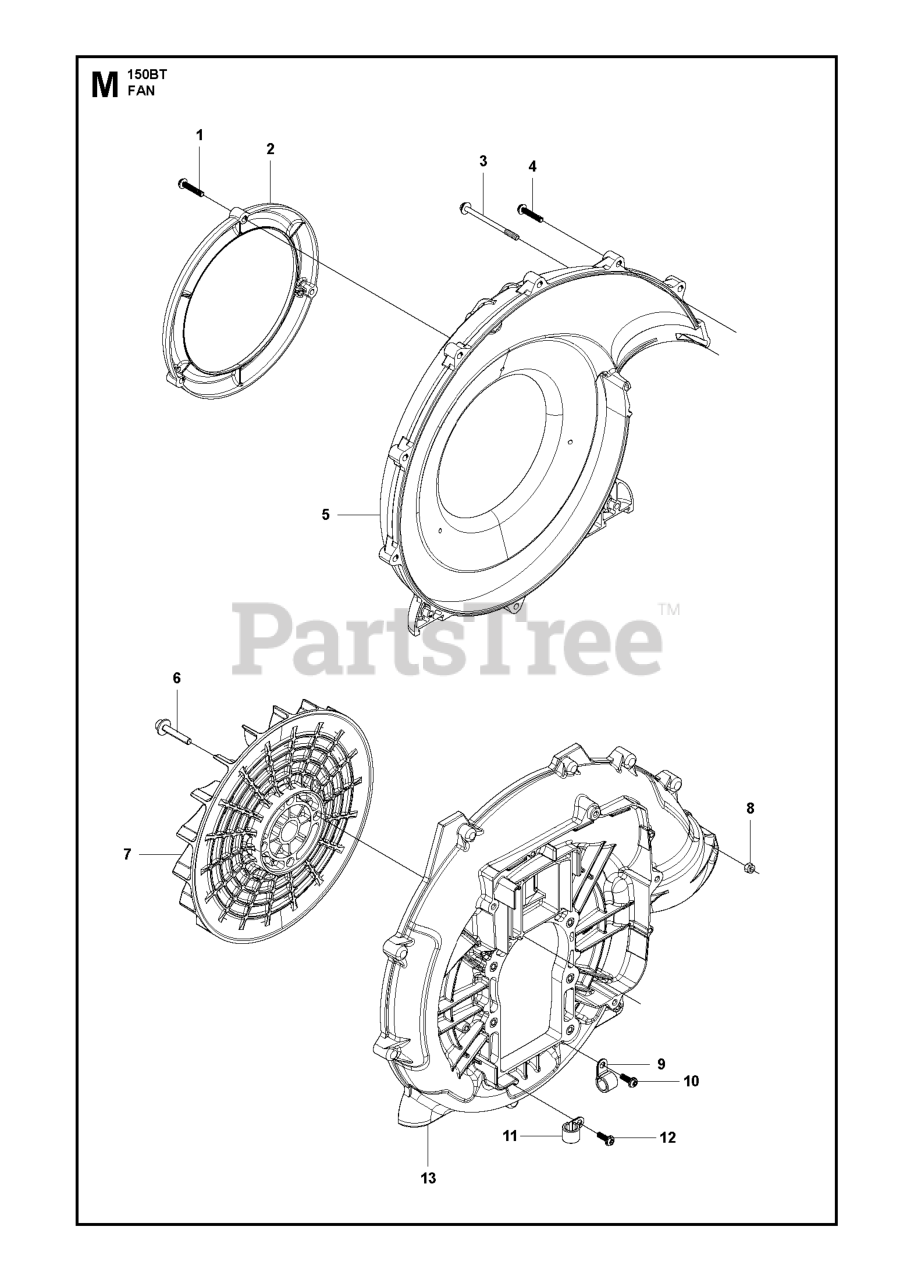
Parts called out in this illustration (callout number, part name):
5	VOLUTE COVER
7	IMPELLER FAN
11	CLAMP
13	FAN HOUSING VOLUTE
